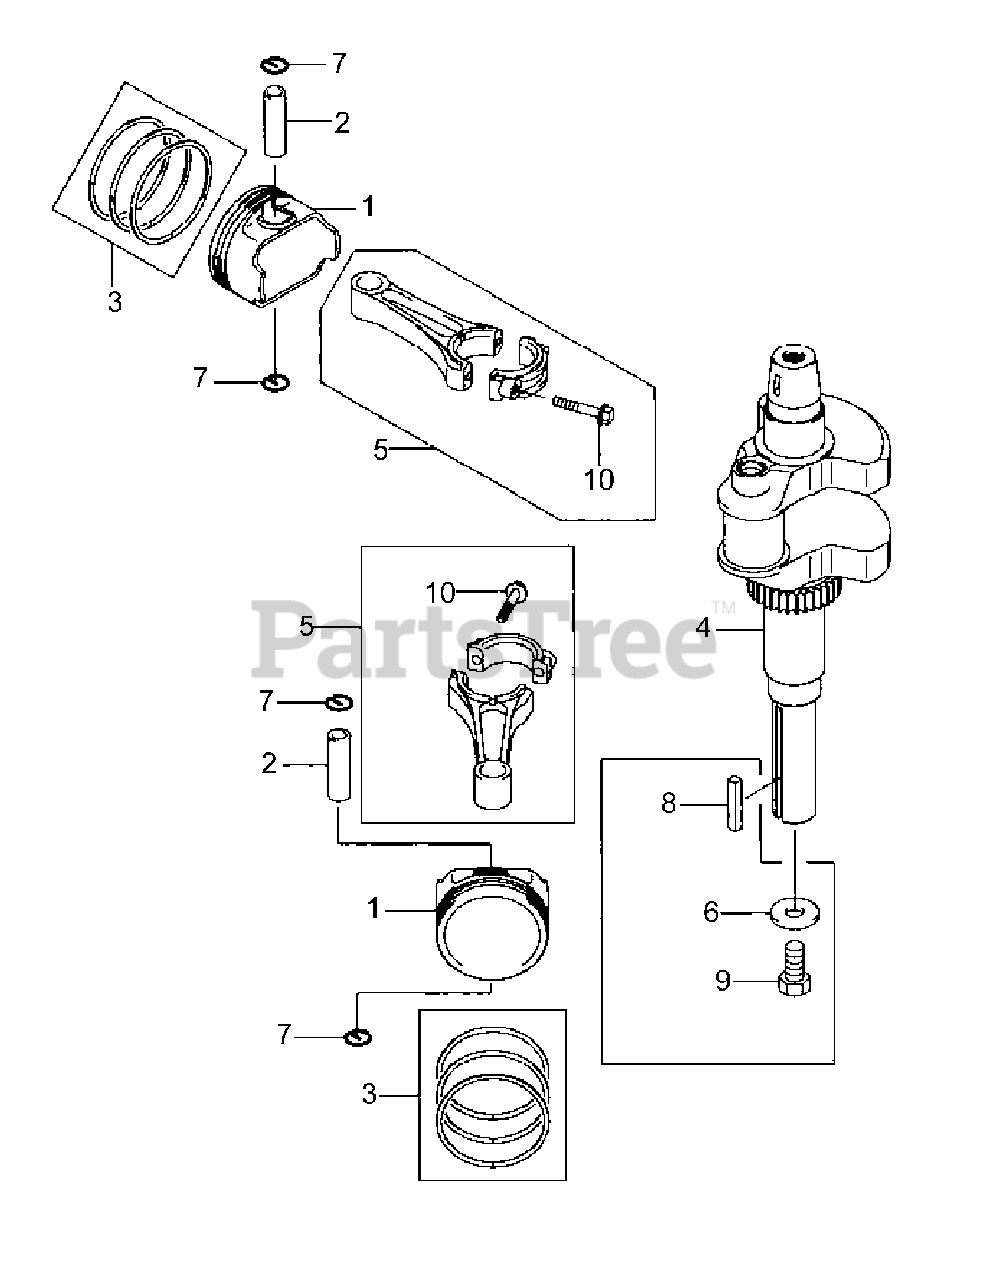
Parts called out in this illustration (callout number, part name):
1	PISTON-ENGINE
1	PISTON-ENGINE .50
3	RING-SET-PISTON
3	RING-SET-PISTON .50
4	CRANKSHAFT-COMP
5	ROD-ASSY-CONNECTING
6	WASHER 12.5x32x3.2
9	BOLT 7/16" x 20
10	BOLT, 6x35
